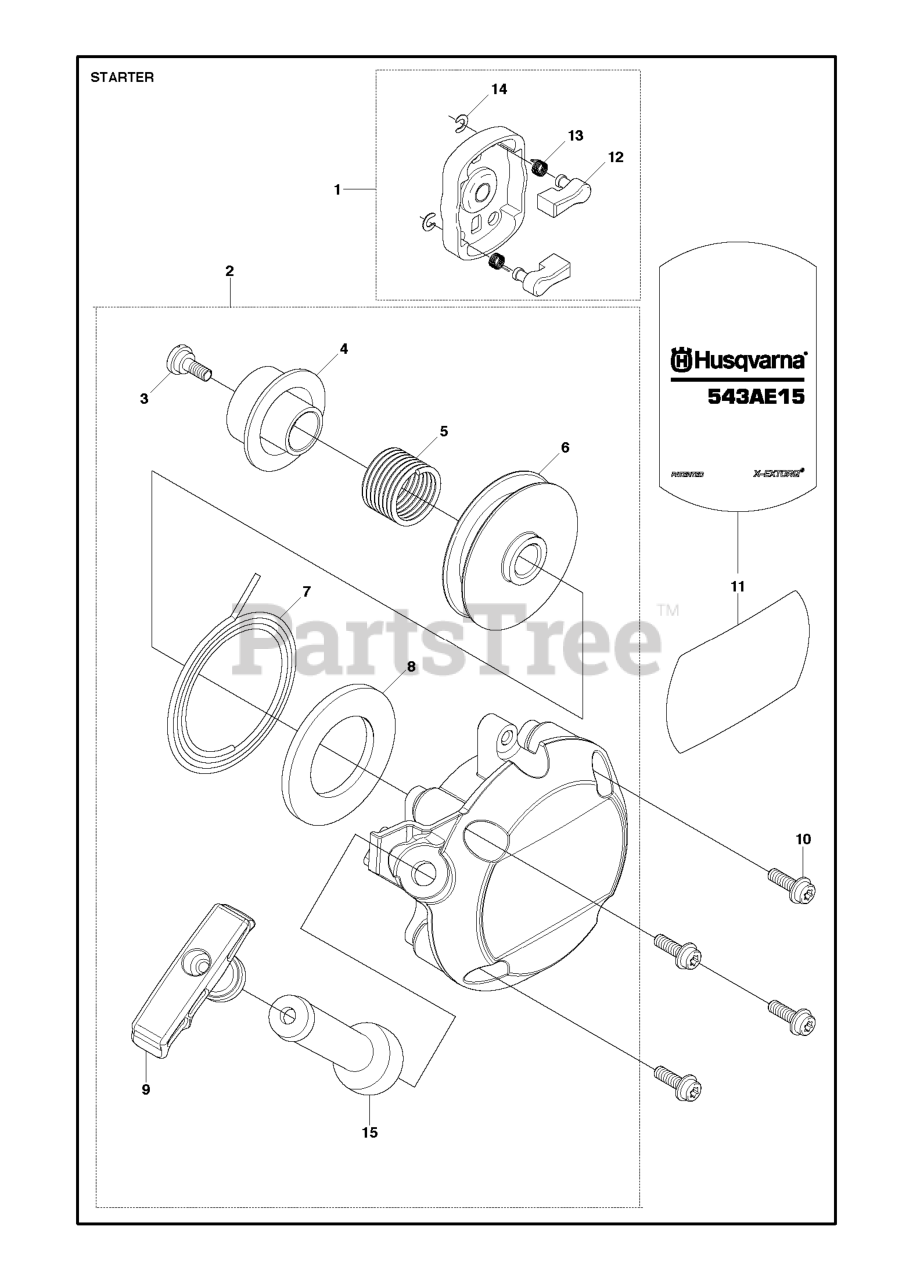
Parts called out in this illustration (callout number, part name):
3	WEIGHT VIBRATION ABSORBER UPPE
5	WASHER STARLOCK WITH CAP
8	LEVER M53 / M48
9	KNOB M53S / M48S HUSQVARNA GRE
10	NUT FLANGE - M6
12	WEIGHT LOWER
15	SCREW
16	THROTTLE CONTROL
17	HANDLE UPPER WITH HOLE
19	HANDLE M53 / M48
22	SCREW RXS B8X9.5
23	LOCKNUT M8
25	CABLE BRAKE BREAK M53
26	DRIVE CONTROL BRAKE M53
27	STARTER ROPE GUIDE KIT
